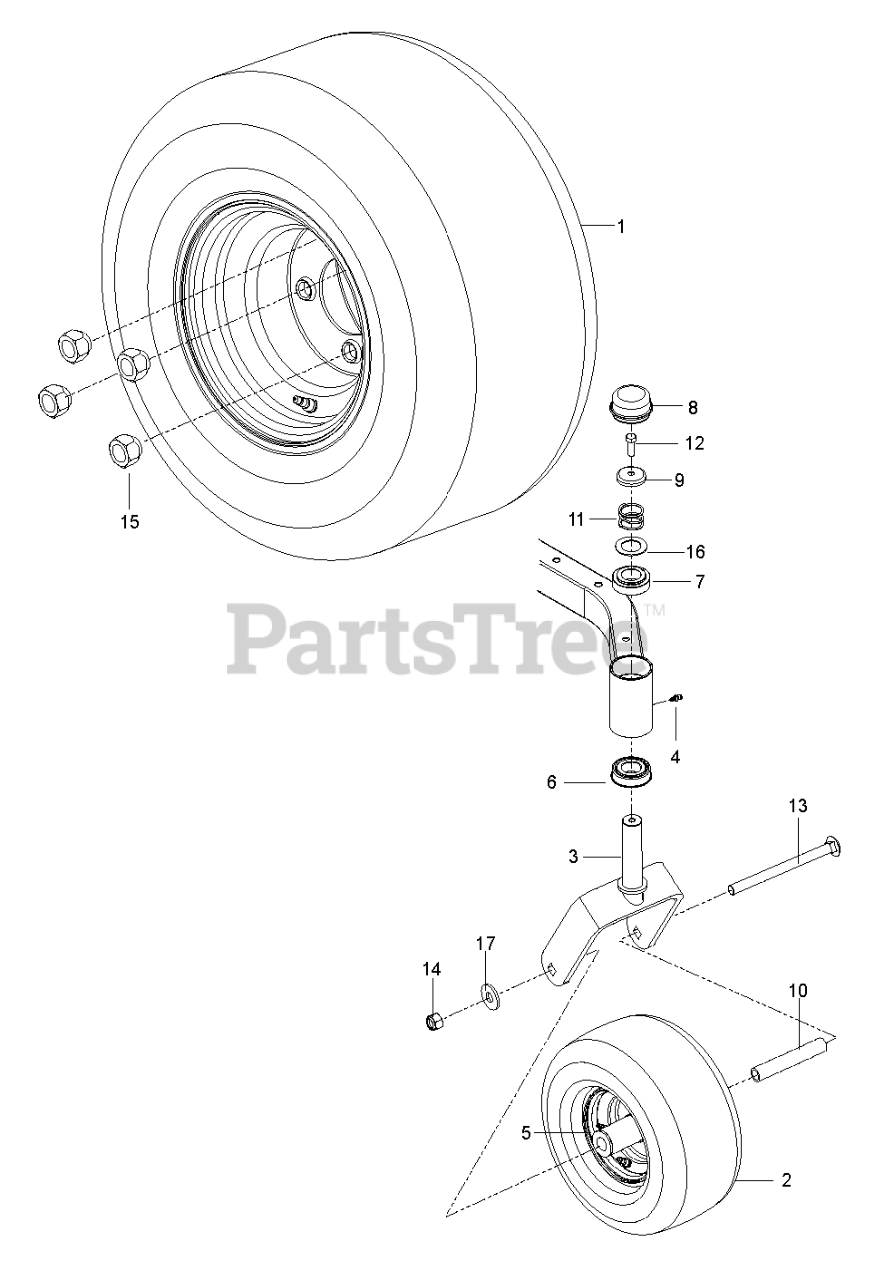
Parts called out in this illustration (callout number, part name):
1	WHEEL.CARLSTAR.18X8.5-8".MS417
2	WHEEL ASSY, WIDE, RZ
3	YOKE.PNT.CASTER.ORG
4	ZERK, 3/16, DRIVE IN
5	ZERK
6	BEARING FLANGED
7	BUSHING, CASTER
8	GREASE CAP
9	CASTER.PLUG
10	SPACER.PIVOT
11	SPRING, CASTER
12	5/16-18X1 HHB G5W/NY
13	RHSNB 1/2-13 X 7.5
14	NUT. 1/2-13 HEX CNTRLK GR 5 ZD
15	NUT.1/2-20.UNF-2B.GR.8.YL
16	WASHER, 1.025 ID X 1.64
17	WASHER.9/16 X 1 3/8 X 12 GA.
